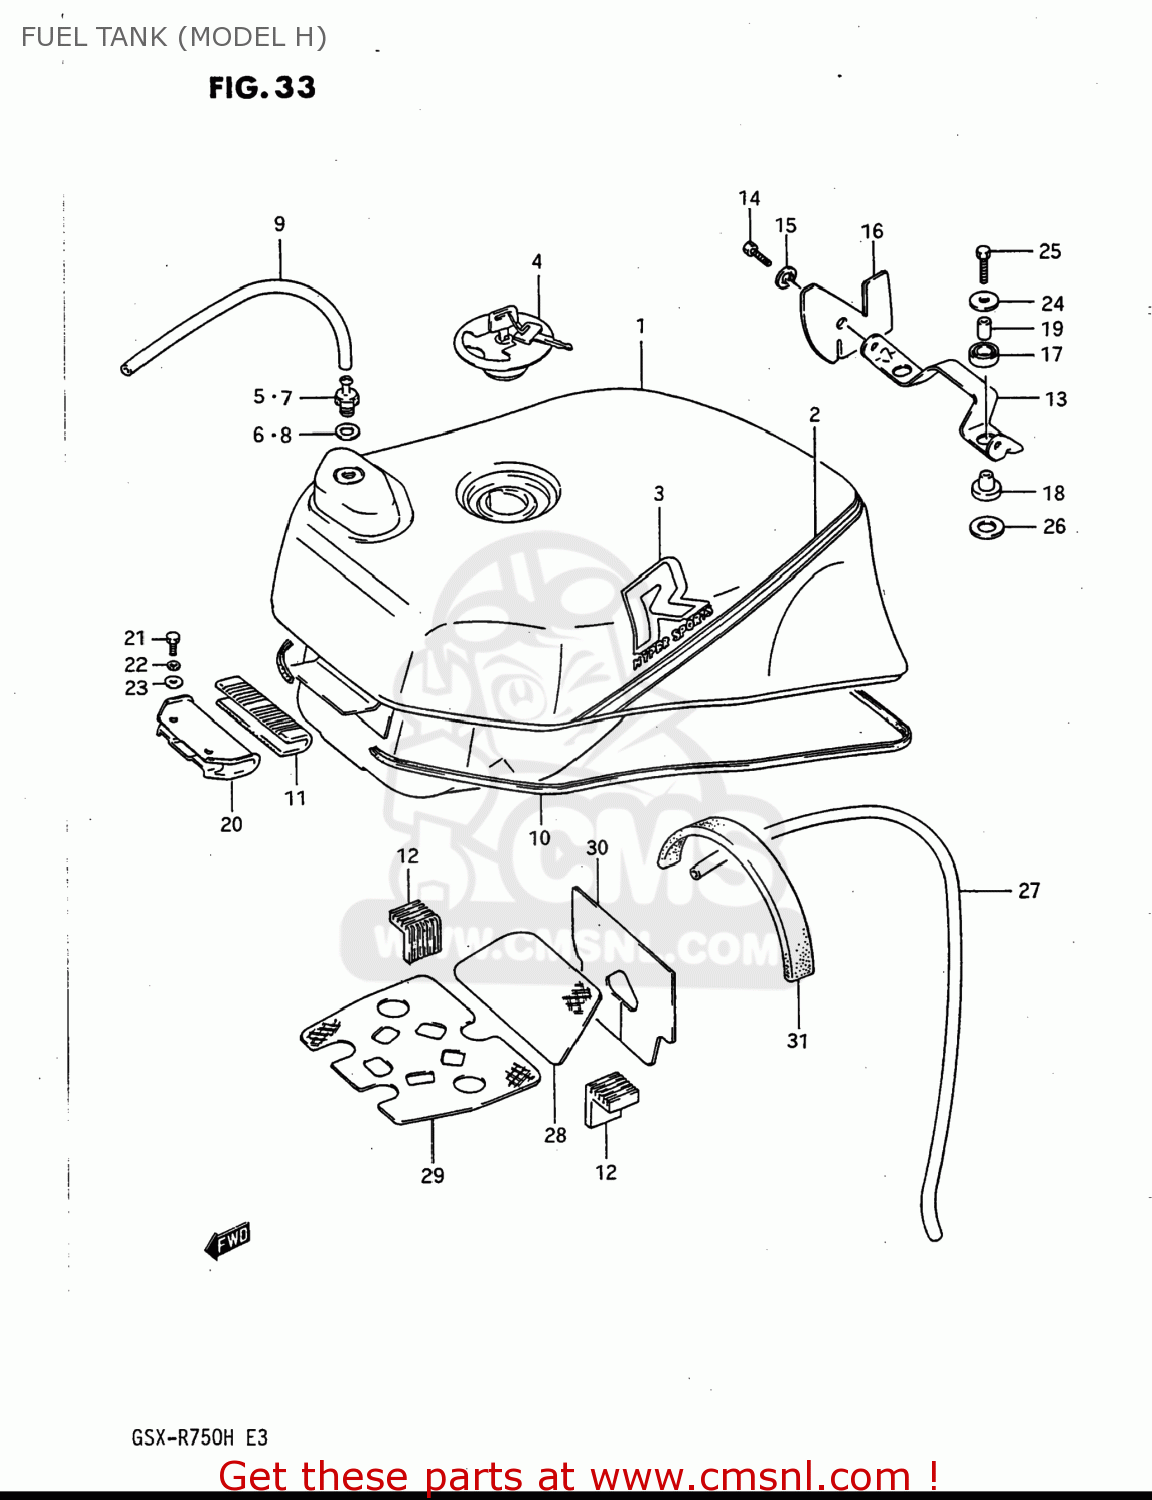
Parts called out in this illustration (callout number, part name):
1	TANK ASSEMBLY,FUEL
2	TAPE SET,FUEL TANK
3	EMBLEM
4	CAP SET,FUEL TANK
5	PLUG,FUEL TANK BREATHER
6	GASKET(12.5X20X2.5) (NAS)
7	(CA) VALVE,FUEL TANK BREATHER
8	GASKET 27X40X2.5 (NAS)
9	HOSE,FUEL
10	MOLDING,FUEL TANK
11	CUSHION,FUEL TANK FR
12	CUSHION,FUEL TANK SIDE
13	BRACKET,SEAT SUPPORT,FRONT
14	BOLT
15	WASHER,LOCK
16	SHIELD,FUEL TANK WIND
17	CUSHION
18	CUSHION
19	SPACER
20	BRACKET,FUEL TANK FR
21	BOLT
22	WASHER,LOCK
23	WASHER
24	WASHER (6.5X24X1.6)
25	BOLT ,6X35
26	WASHER (12.5X24X1.6)
27	HOSE,FUEL
28	SHIELD,FUEL TANK HEAT
29	SHIELD,FUEL TANK HEAT
30	SHIELD,HEAT NO.1
31	SHIELD,TANK & CLEANER
